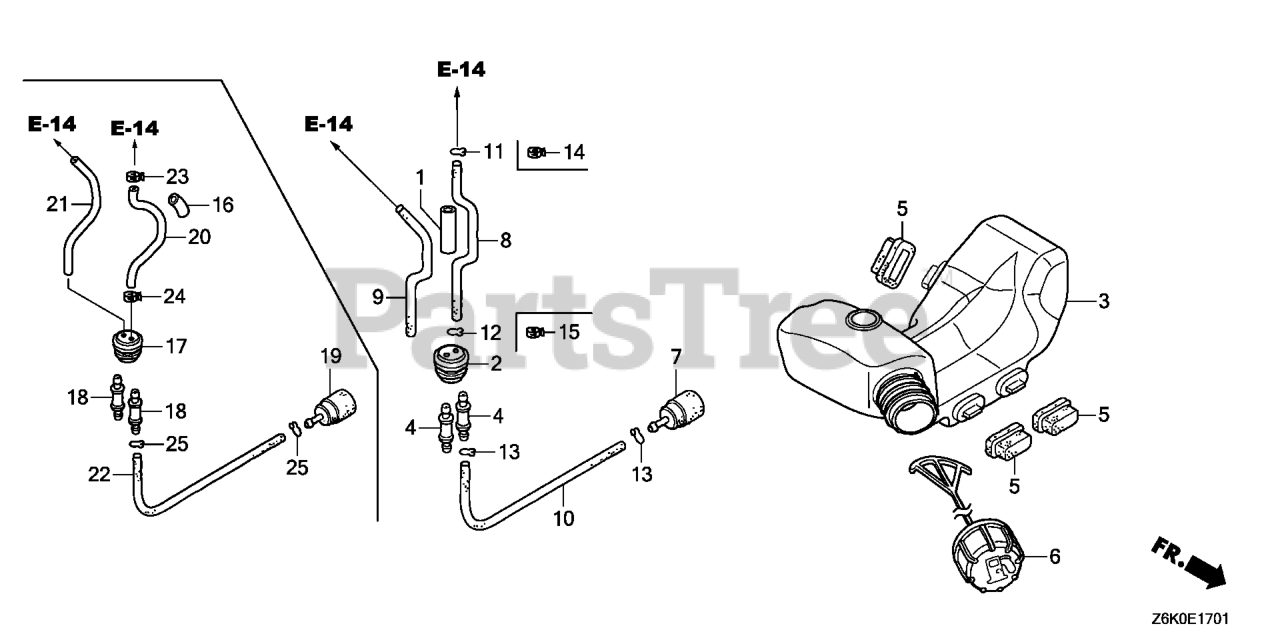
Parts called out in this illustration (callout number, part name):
3	TANK, FUEL
5	RUBBER, TANK MOUNTING
6	CAP ASSY., FUEL TANK
16	PROTECTOR, TUBE
17	GROMMET, FUEL TUBE
18	JOINT, FUEL TANK
19	FILTER, FUEL
20	TUBE, FUEL
21	TUBE, FUEL RETURN
22	TUBE A, FUEL
23	CLAMP, TUBE
24	CLAMP, TUBE
25	CLIP, TUBE (B1 5)
